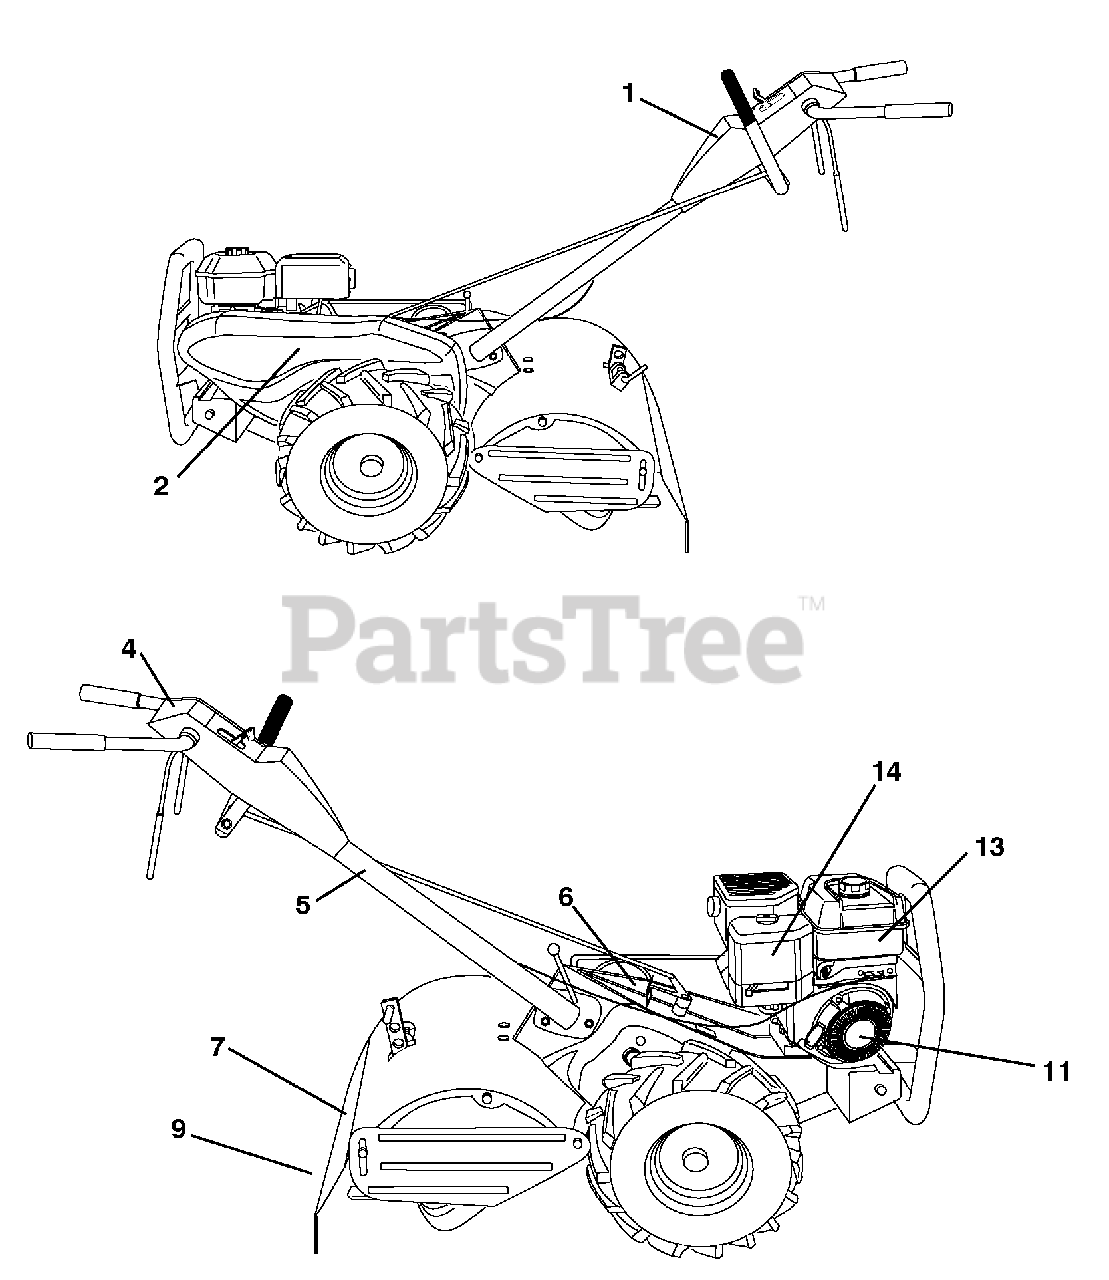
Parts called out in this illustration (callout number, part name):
1	Decal, CNTRL PNL
2	Decal, Decal, Blt Grd
4	Decal, Instruction, Tilling
5	Decal, Hand Placement
6	Decal, Shift Indicator
7	Decal, Caution
9	Decal, Warning, Rotating Tines
11	Decal, Rewind
13	Decal, B&S Tank
14	Decal, B&S, Air Cleaner
14	Manual, Operator's, English/French
14	Manual, Repair Parts, English/French
